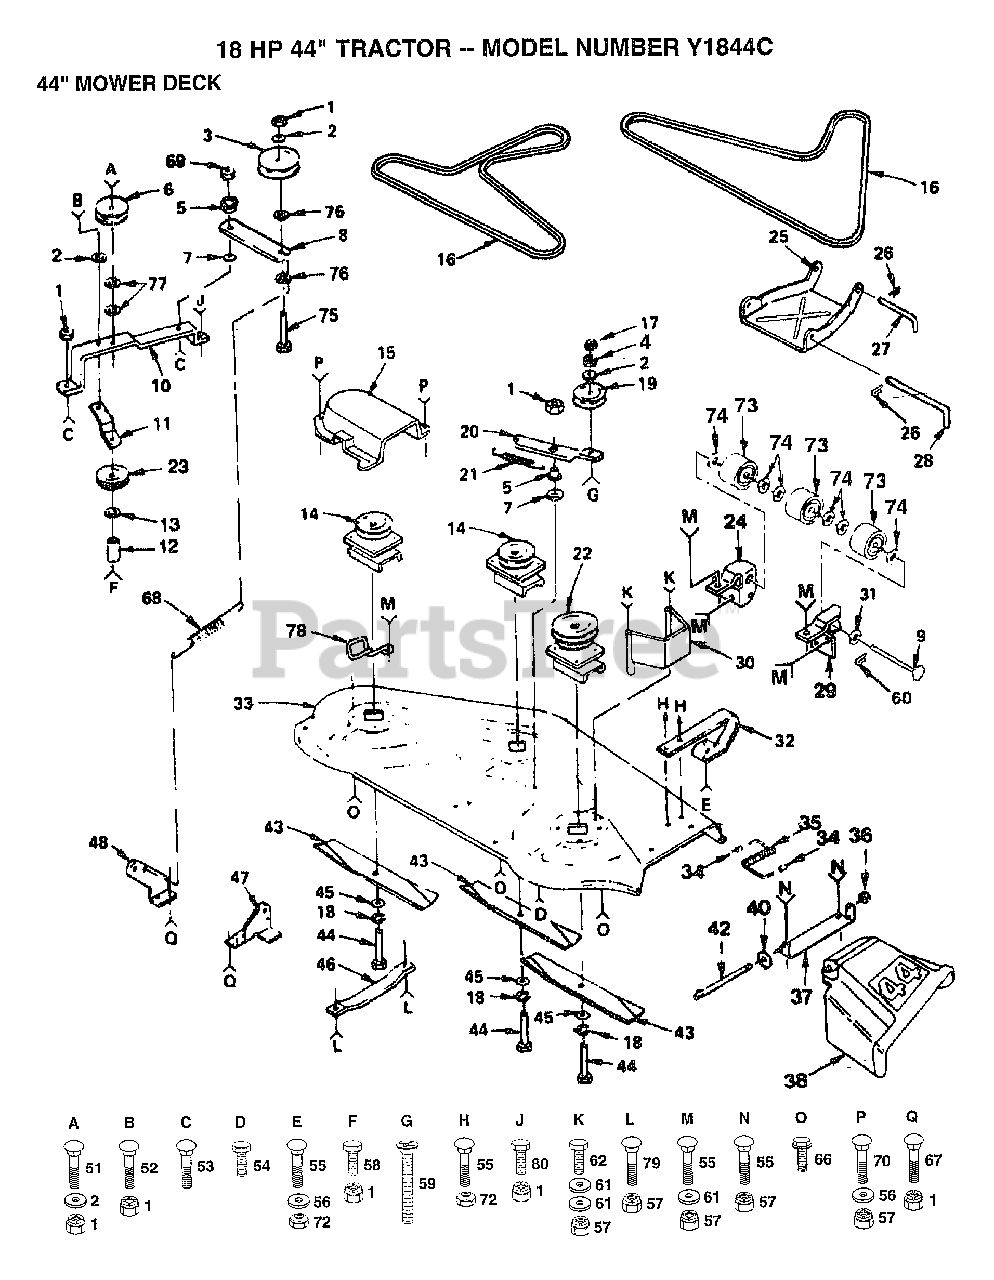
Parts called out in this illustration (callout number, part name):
2	WASHER
3	PULLEY IDLER
4	LOCKWASHER
5	SPACER RETAINER
6	IDLER-INSIDE T
7	"WASHER, WEAR LT"
8	ARM IDLER
9	PIVOT PIN T
10	"SUPPORT YT, BAR"
11	BRACE-IDLER YT
12	SPACER
13	WASHER
15	GUARD YT
16	BELT-V.79.1.MWR
17	NUT.HEX.3/8-16UNC
19	IDLER.FLAT.GTV
20	ARM-IDLER YT
22	JACKSHAFT
23	IDLER-FLAT T
24	BRACKET LH YTH
25	LINK.PARALLEL
26	SPRING.RETAINER
27	"ROD, FRT. PARAL T"
28	HINGE PIN T
29	BRACKET RH YTH
30	GUARD BELT HYT
32	RUNNER.RH
34	CAP-SLEEVE LT
35	SPRING TORSION
36	NUT PUSH M
37	BRKT DEFLECTOR
38	DEFLECTOR SHIELD
40	WASHER
42	ROD-HINGE T
44	BOLT.3/8-24X1-1/2
45	WASHER
46	RUNNER-LH M
47	BRKT SUSP REAR RH
48	BRKT SUSP REAR LH
51	BOLT
53	BOLT
55	BOLT
56	WASHER
58	BOLT - HEX 3/8 - 16 X 3
59	SCREW YT
60	COTTER PIN
61	WASHER M
62	BOLT
66	SCREW
67	BOLT
68	"SPRING.EXT.8.5"""
69	LOCKNUT
73	ROLLER T
74	WASHER T
75	BOLT
76	WASHER
77	WASHER
78	BELT RETIANER
79	BOLT
80	BOLT
